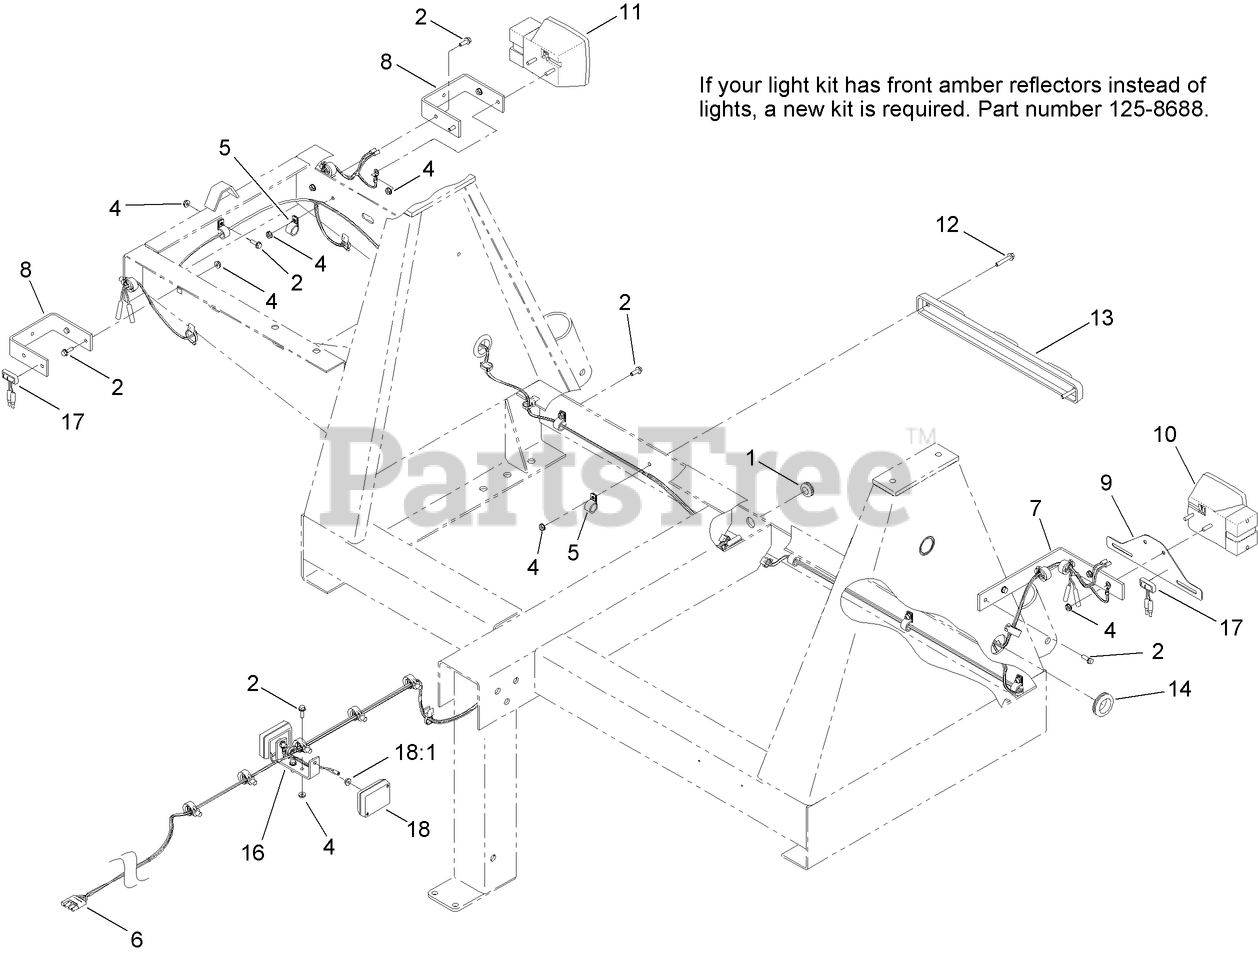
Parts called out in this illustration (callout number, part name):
1	GROMMET
2	SCREW-HHF
4	NUT-KEPS
5	CLAMP-CABLE
6	HARNESS-WIRE
7	BRACKET-L
8	BRACKET-U
9	HOLDER-PLATE, LICENSE
10	LIGHT-TAIL, LH
11	LIGHT-TAIL, RH
12	SCREW-HHF
13	LIGHT-IDENTIFICATION, TRAILER
14	GROMMET
16	BRACKET-LIGHT, END DUMP
17	LAMP-AMBER
18	LAMP-MARKER, FRONT SIDE
18:1	NUT-KEPS
